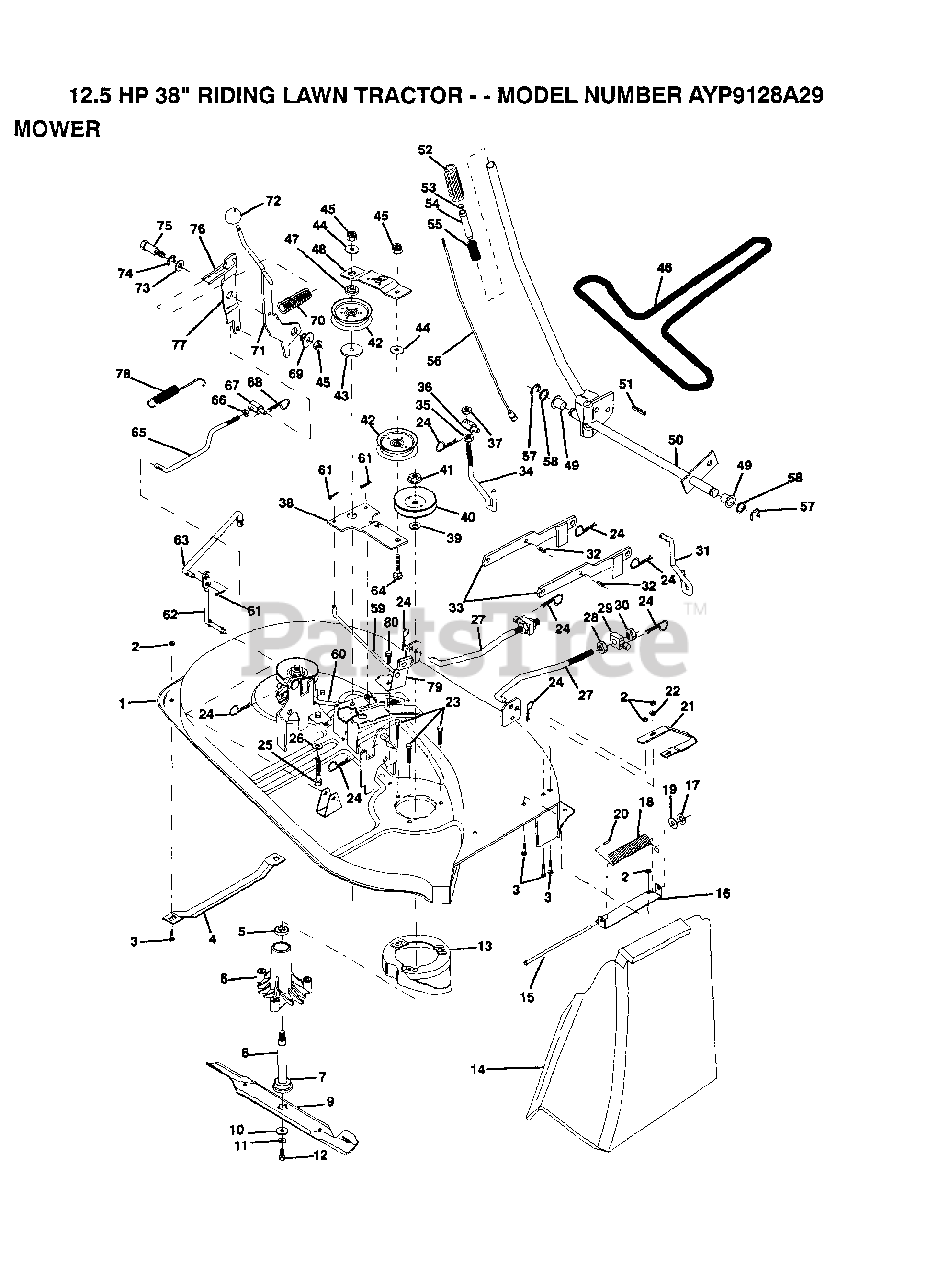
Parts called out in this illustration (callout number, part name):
3	BOLT
4	RUNNER-LH M
5	BEARING
6	HSG ASM MANDREL
7	BEARING.BALL
10	WASHER BLADE
12	BLADE BOLT
14	DEFLECTOR-SHLD T
15	ROD-HINGE T
17	NUT PUSH M
19	WASHER
20	CAP-SLEEVE LT
21	RUNNER RH
22	WASHER M
25	BOLT
26	WASHER GT
27	LINK.FRONT
28	NUT
29	TRUNION
30	NUT.LK.W/WSH.1/2.
31	LINK LIFT RH
32	SPRING PIN
33	SUSP ARM REAR
34	LIFT LINK LH
35	NUT
38	IDLER ARM ASSY
39	WASHER
42	FLAT IDLER PULLEY
43	SPACER RETAINER
44	WASHER GT
46	BELT-V.88.12.MW
47	RETAINER SPACER
48	IDLER ARM STIFF
49	NYLON BEARING
50	LIFT SHAFT ASM
51	PIN-GROOVE LT
52	GRIP
58	WASHER
59	BRAKE ROD RH
60	BRAKE ROD LH
62	PIVOT ROD
63	CLUTCH ROD SECOND
64	BOLT
66	NUT
67	TRUNION
68	RETAINER M
69	BUSHING
73	WASHER
74	RING
75	SHOULDER BOLT
76	SPRING KEEPER
77	CLUTCH ARM SECOND
78	RETURN SPRING
79	BRAKE ASM
80	SCREW
